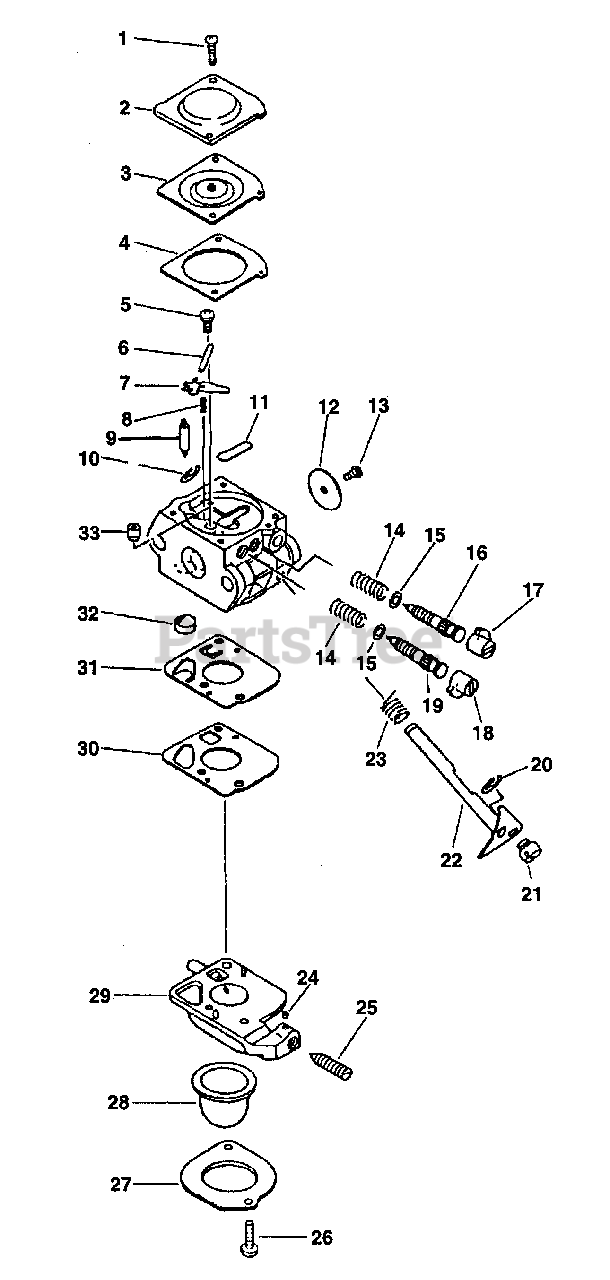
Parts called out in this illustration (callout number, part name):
2	Cover, metering diaphragm
3	Diaphragm, metering
4	Gasket, metering diaphragm
6	Pin, metering arm
7	Lever, metering
8	Spring, metering lever
9	Valve, inlet needle
11	Plug, welch
12	Valve, throttle
14	Spring, needle
16	Needle, low speed
17	Limiter, cap l.s.
18	Limiter, cap h.s.
19	Needle, high speed
22	Shaft, throttle
23	Spring, throttle return
24	Piece, friction
25	Screw, idle adjust
27	Retainer, purge pump
28	Pump, purge
29	Base, purge
30	Gasket, fuel pump
31	Diaphragm, fuel pump
32	Strainer
33	Nozzle, check valve
